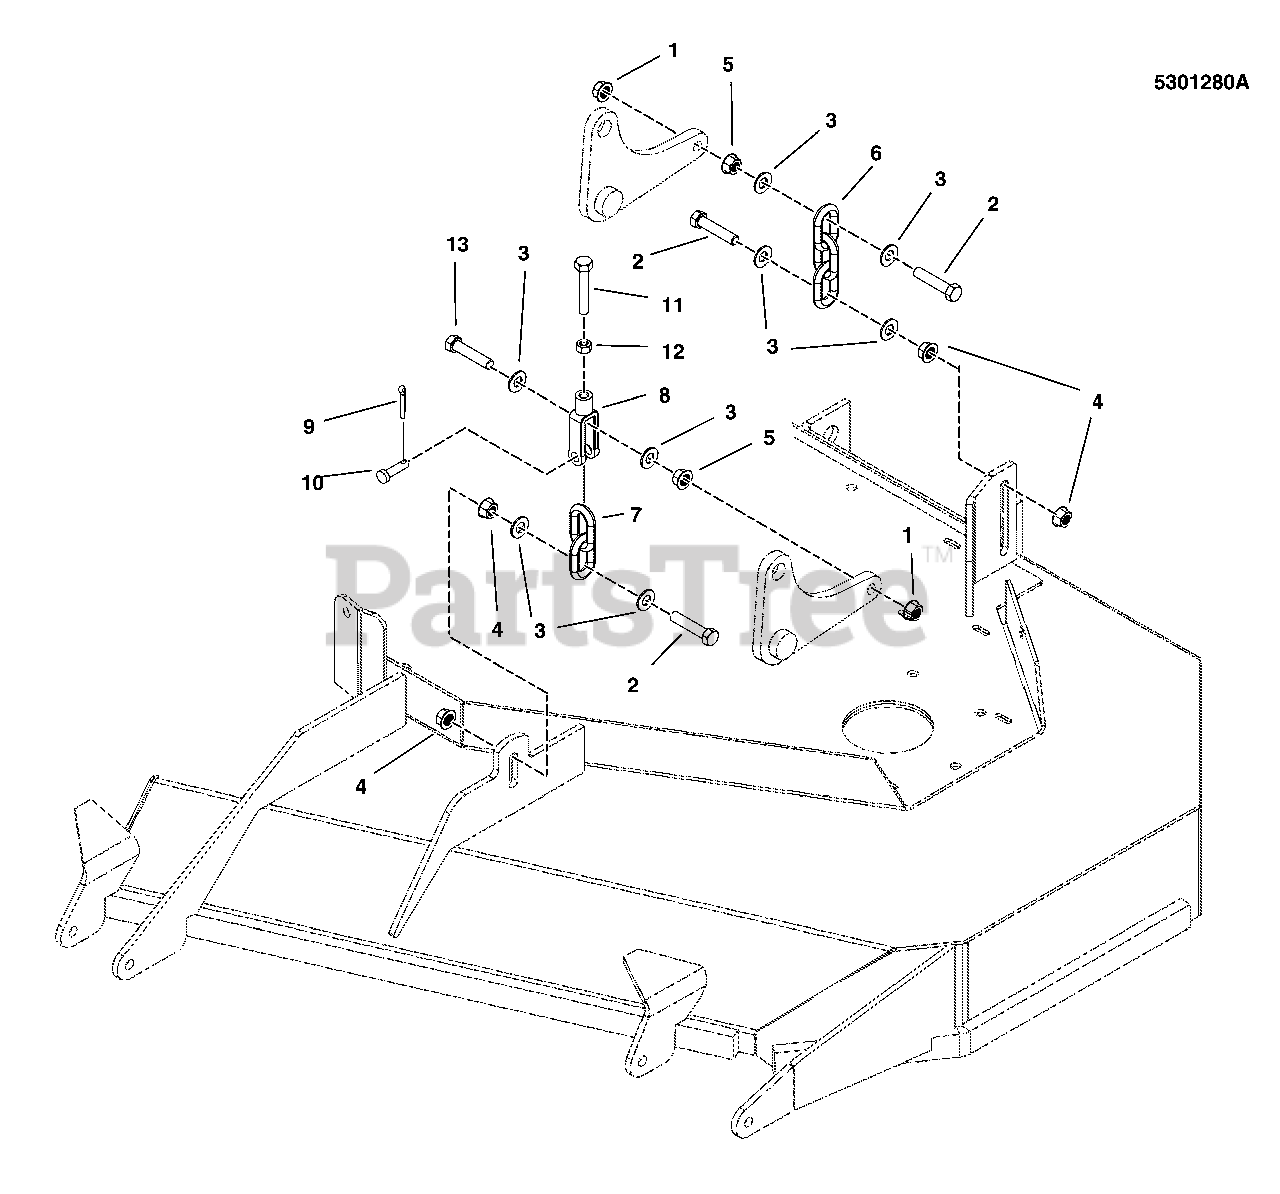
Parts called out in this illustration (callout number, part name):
1	NUT, 3/8-16 HEX NYLOCK FLANGE
2	BOLT, 3/8-16 X 1-3/4" GD5 CZ
3	WASHER, 3/8 SAE
4	NUT, 3/8-16 HEX SERRATED FLANGE
5	NUT, 3/8-16 HEX JAM
6	CHAIN, 5/16 GD30, 3 LINKS
7	HANGER, FRONT DECK - 2 LINK
8	CLEVIS, 5/16-18, 3/8 PIN HOLE
9	PIN, CLEVIS, 3/8 X 1-1/8
10	PIN, COTTER, 1/8 X 3/4
11	BOLT, 5/16-18 X 2 GD5 TFL
12	NUT, 5/16-18 HEX JAM
13	BOLT, 3/8-16 X 2, GD5, CZ
